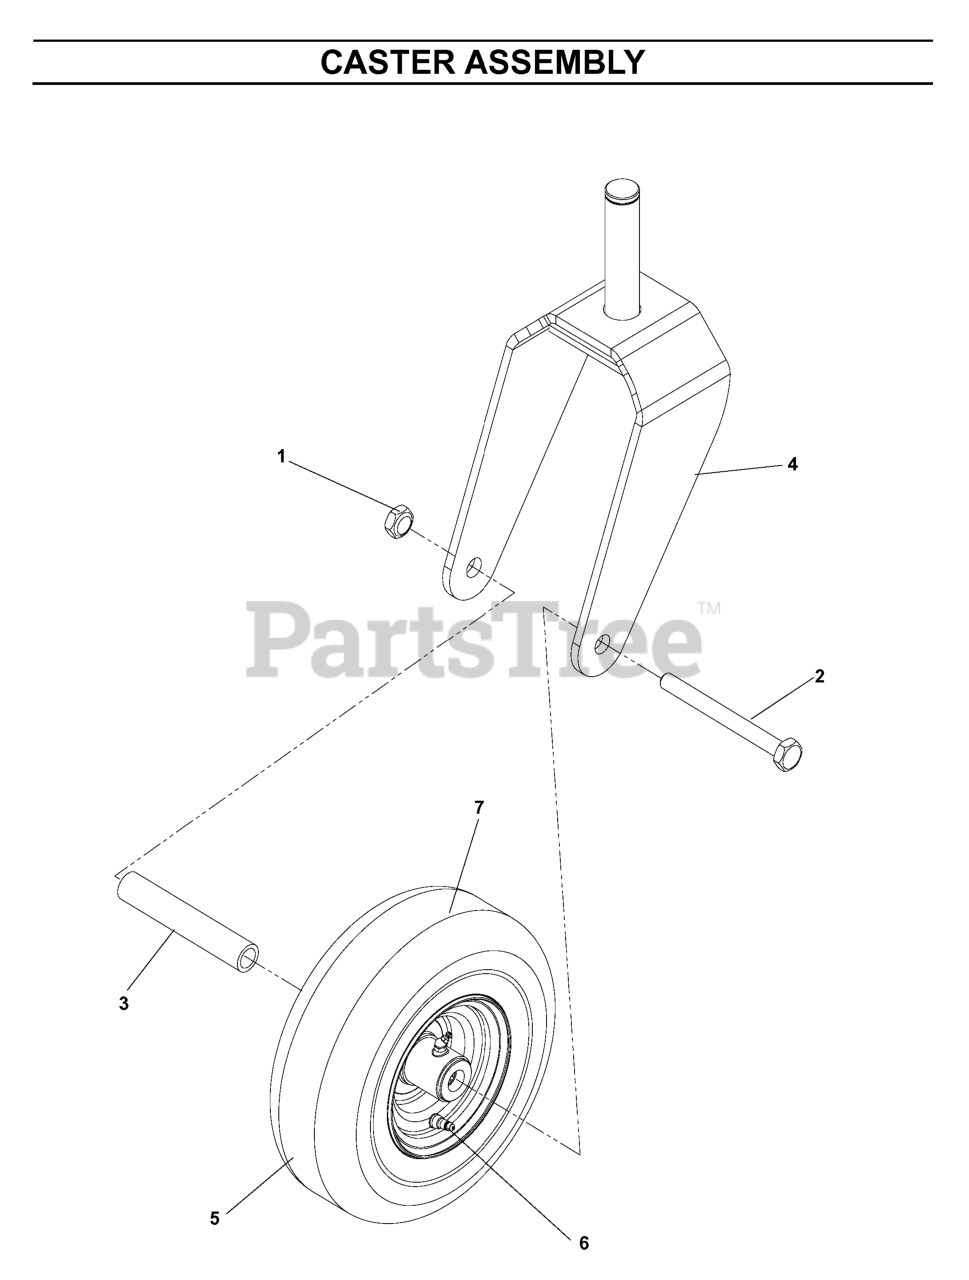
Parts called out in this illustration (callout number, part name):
1	NUT 1/2-13 HEX NYLOC ZD
2	HCS 1/2C X 5 1/2
4	CASTER WLDT
5	TIRE COMPLETE
6	VALVE STEM TR-412
7	TIRE - CASTER
